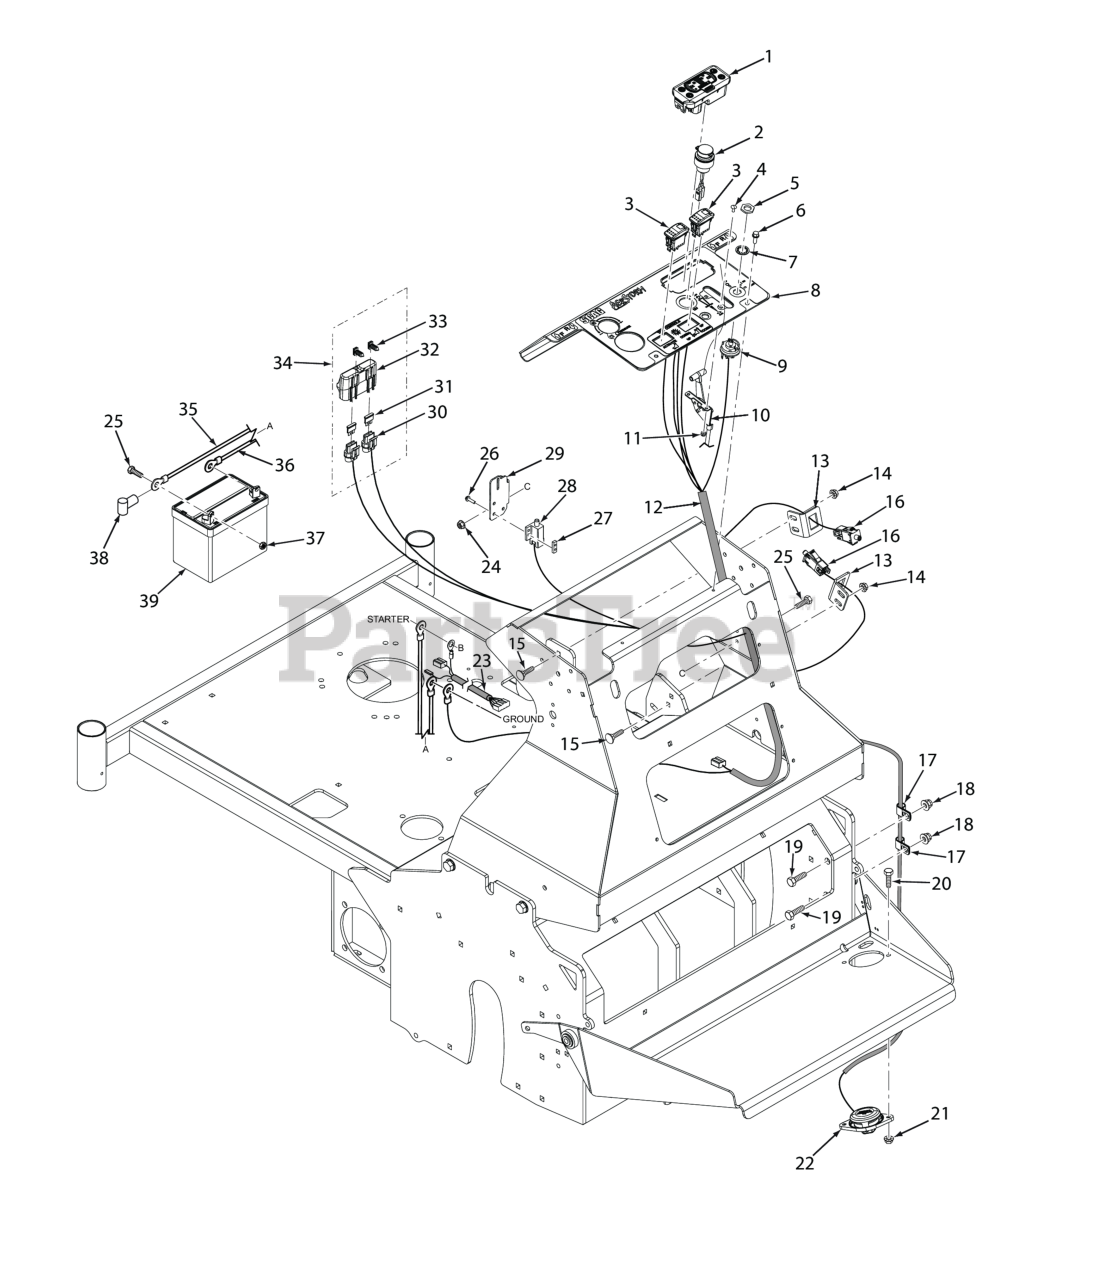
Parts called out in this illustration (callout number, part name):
1	Tiger Eye, Cluster Gauge
2	Power Plug, 12V
3	Switch, Rocker - Lighted
4	Bolt, Carriage #10-24 x 1/2"
5	Nut, 5/8-32 Special
6	Screw, Self-Tapping 1/4-20 x 3/4
7	LOCK WASHER, 5/8" INTERNAL TOOTH
8	Instrument Panel w/Decal
9	KEY SWITCH(INCLUDES MOUNTING HARDWARE)
10	Throttle Cable
11	Nut, Elastic Stop #10-24
12	Wire Harness
13	Bracket, Height Switch
14	Nut, Serrated Flange 5/16-18 (Right Front Engine Mounting, Briggs and Kohler Only)
15	Bolt, 5/16-18 x .75 RHSN Carriage
16	Switch, Plunger, Double Pole, Snap
17	Wire Loom
18	HEX NUT, ELASTIC STOP LOCK, 5/16-18
19	BOLT, SERRATED FLANGE HEX HEAD 5/16-18 X 3/4"
20	Bolt, Heax Head 5/16-18 x 1" (48V / 52V)
21	Nut, Flange Head Elastic Stop 5/16-18
22	Switch, Foot
23	Wire Harness Adapter, Kohler - 23CV
24	NUT, 1/4-20 SERRATED FLANGE HEX HEAD
25	BOLT, HEX HEAD, 1/4-20 X 3/4 GR.5
26	Screw, Hex-Slotted Washer Head #10 32 x 3/4"
27	Plate, Threaded
28	Switch, Interlock (see below)
29	Bracket, Neutral Switch
30	Fuse Holder Assembly
31	FUSE, 20 AMP BLADE TYPE AUTOMOTIVE
32	Cover, Sealed Double
33	Mounting Bracket, Operator Presence
34	Double Fuse Assy.
35	Cable, Battery - Red 60" w/Braid
36	Battery Cable, Black
37	Nut, 1/4 - 20 Hex
38	RUBBER BOOT
39	Battery, 350 CCA (not available through Scag)
